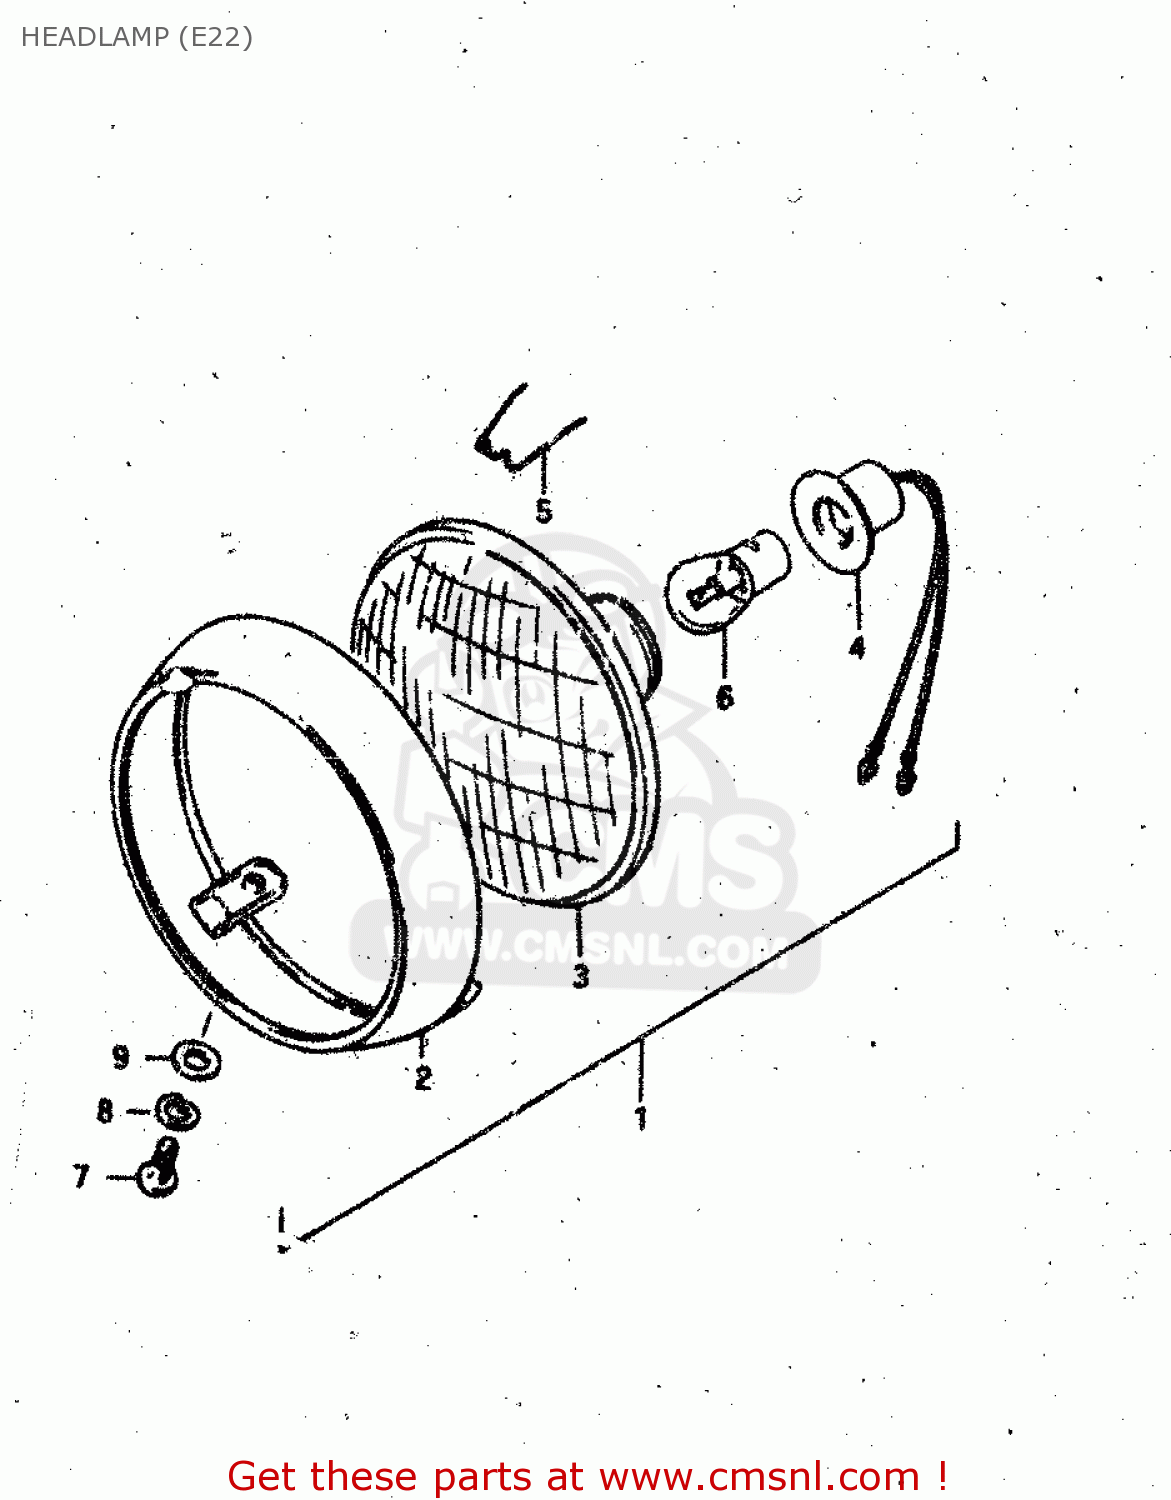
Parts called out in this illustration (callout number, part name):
1	HEADLAMP ASSY
2	RIM
3	UNIT
4	SOCKET
5	SPRING
6	BULB (6V,15W)
7	SCREW
8	LOCK WASHER
9	WASHER
